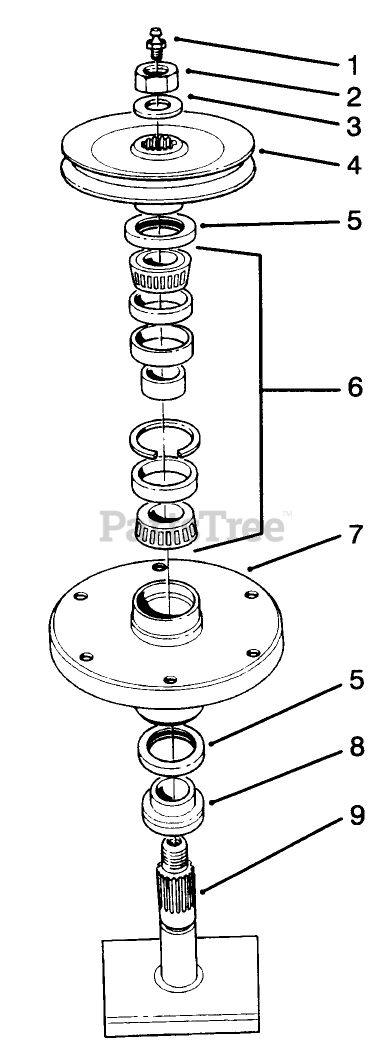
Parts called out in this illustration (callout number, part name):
1	FITTING-GREASE
2	NUT-HEX
3	WASHER
4	PULLEY & HUB WA
5	SEAL-OIL
6	BEARING ASM
7	HOUSING-SPINDLE
8	SPACER
9	SHAFT
